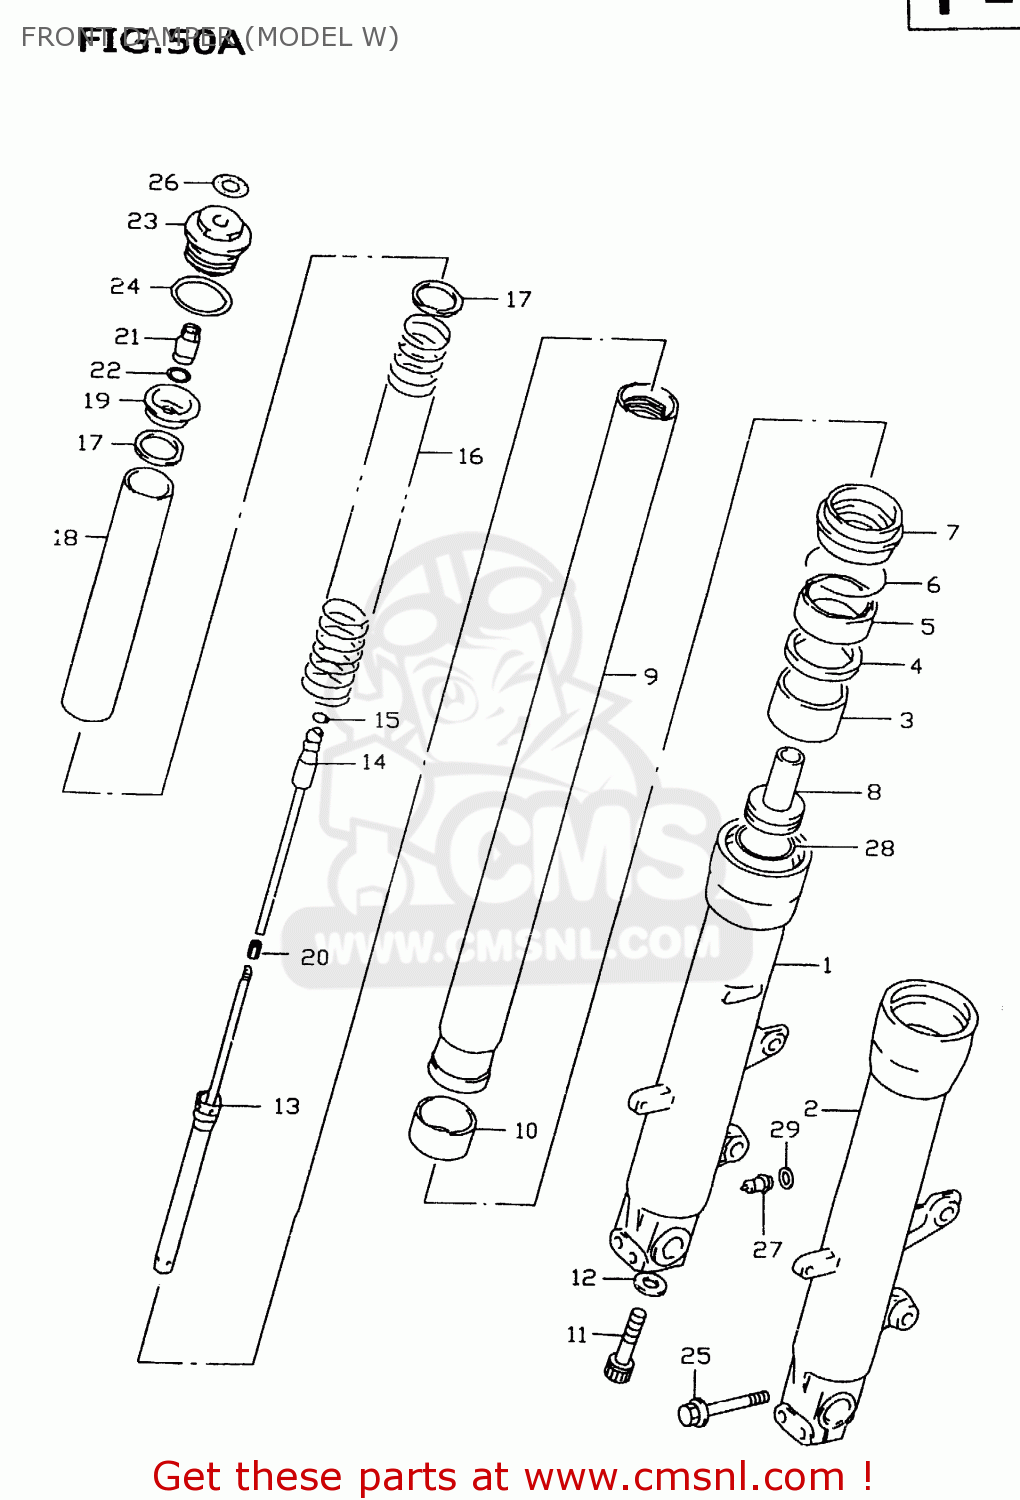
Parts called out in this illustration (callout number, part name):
1	TUBE,OUTER,R
2	TUBE,OUTER,L
3	BUSH,GUIDE
4	SPACER,SEAL
5	SEAL,OIL
6	RING,OIL SEAL STOPPER
7	SEAL,DUST
8	PIECE,OIL LOCK
9	TUBE,INNER
10	BUSH,SLIDE
11	BOLT
12	WASHER(10X15X1.5)
13	ROD,FRONT DAMPER
14	ROD,ADJUST
15	O RING(D:1.9,ID:3.8)
16	SPRING,FR
17	JOINT,SPRING
18	COLLAR,SPRING
19	SEAT,SPRING UPR
20	NUT
21	ADJUSTER,SPRING
22	O RING(D:2.5,ID:13.8)
23	BOLT,FORK
24	O RING
25	BOLT
26	LABEL
27	PIECE,ADJUST
28	O RING
29	LABEL,ADJUST PIECE LWR
